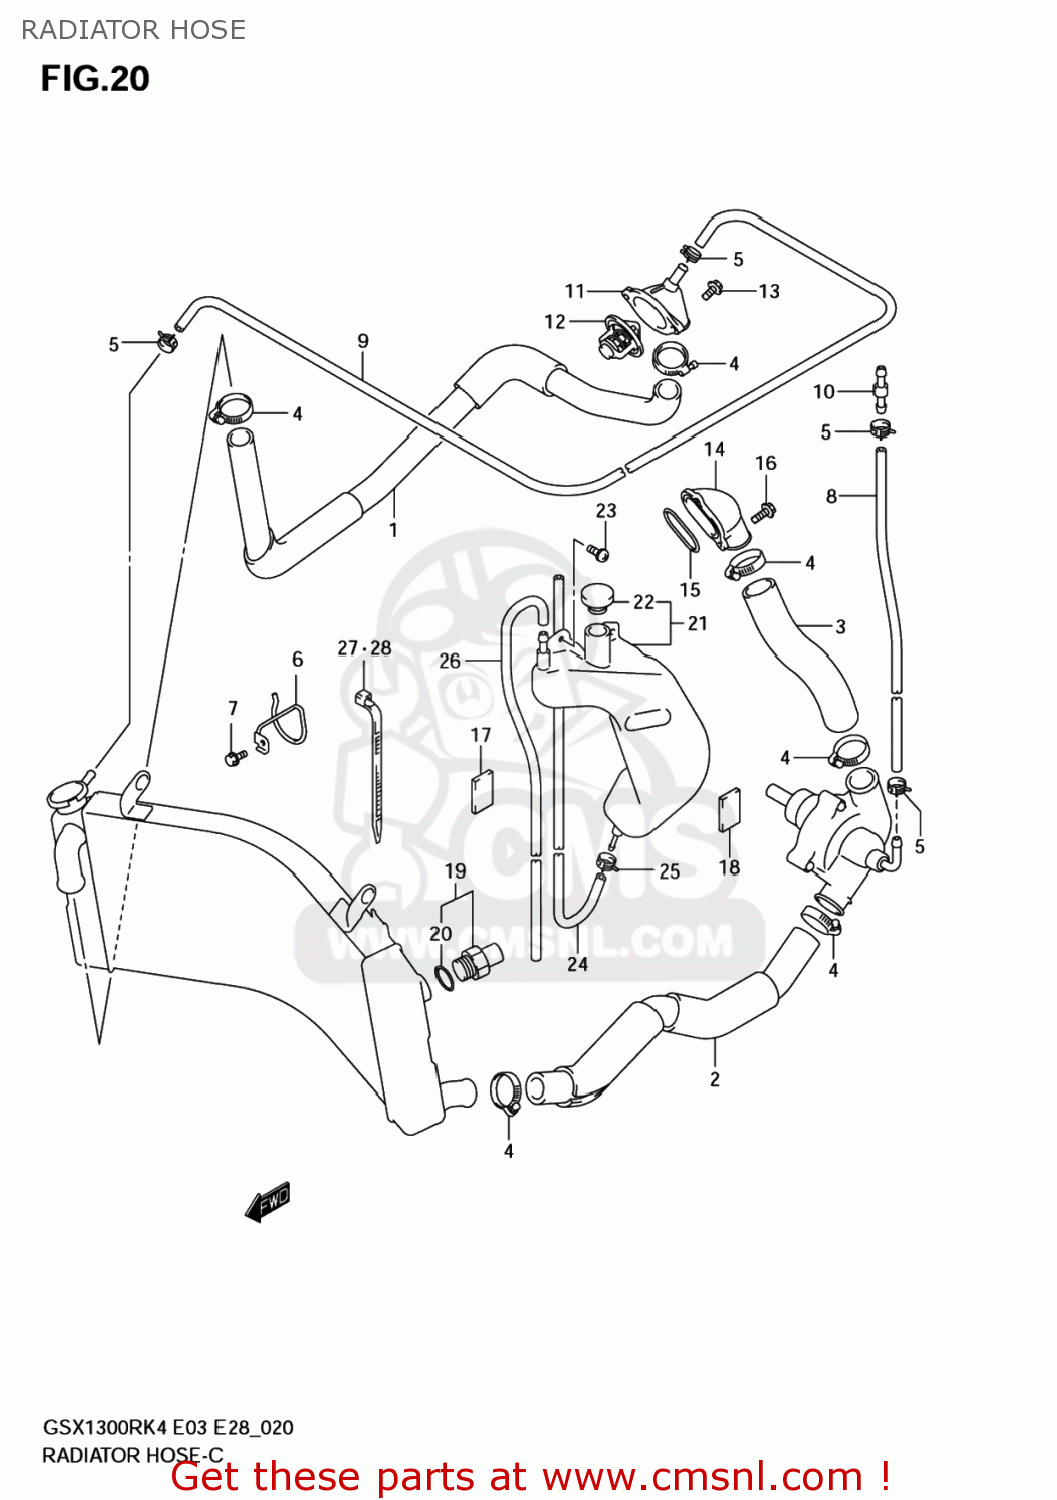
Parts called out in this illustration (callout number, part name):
1	HOSE,RADIATOR INLET
2	HOSE,RADIATOR OUTLET
3	HOSE,CYLINDERL INLET
4	CLAMP
5	CLAMP
6	CLAMP,RADIATOR INLET HOSE
7	BOLT
8	HOSE,WATER BYPASS NO.1
9	HOSE,WATER BYPASS NO.2
10	BOLT UNION
11	COVER,THERMOSTAT
12	THERMOSTAT,WATER 82 DEG
13	SCREW
14	CONNECTOR,CYL.
15	O RING,CYL WATER CONNECTOR
16	BOLT
17	CUSHION,HEAD LAMP HOUSING
18	CUSHION,FR FENDER
19	SWITCH,RADIATOR FAN
20	O-RING
21	TANK ASSY,RESERVOIR
22	CAP,RESERVOIR TANK
23	SCREW(6X20)
24	HOSE,RESERVOIR TANK
25	CLIP
26	HOSE,RESERVOIR TANK OUTLET
27	CLAMP(L:165)
28	CLAMP(L:165)
